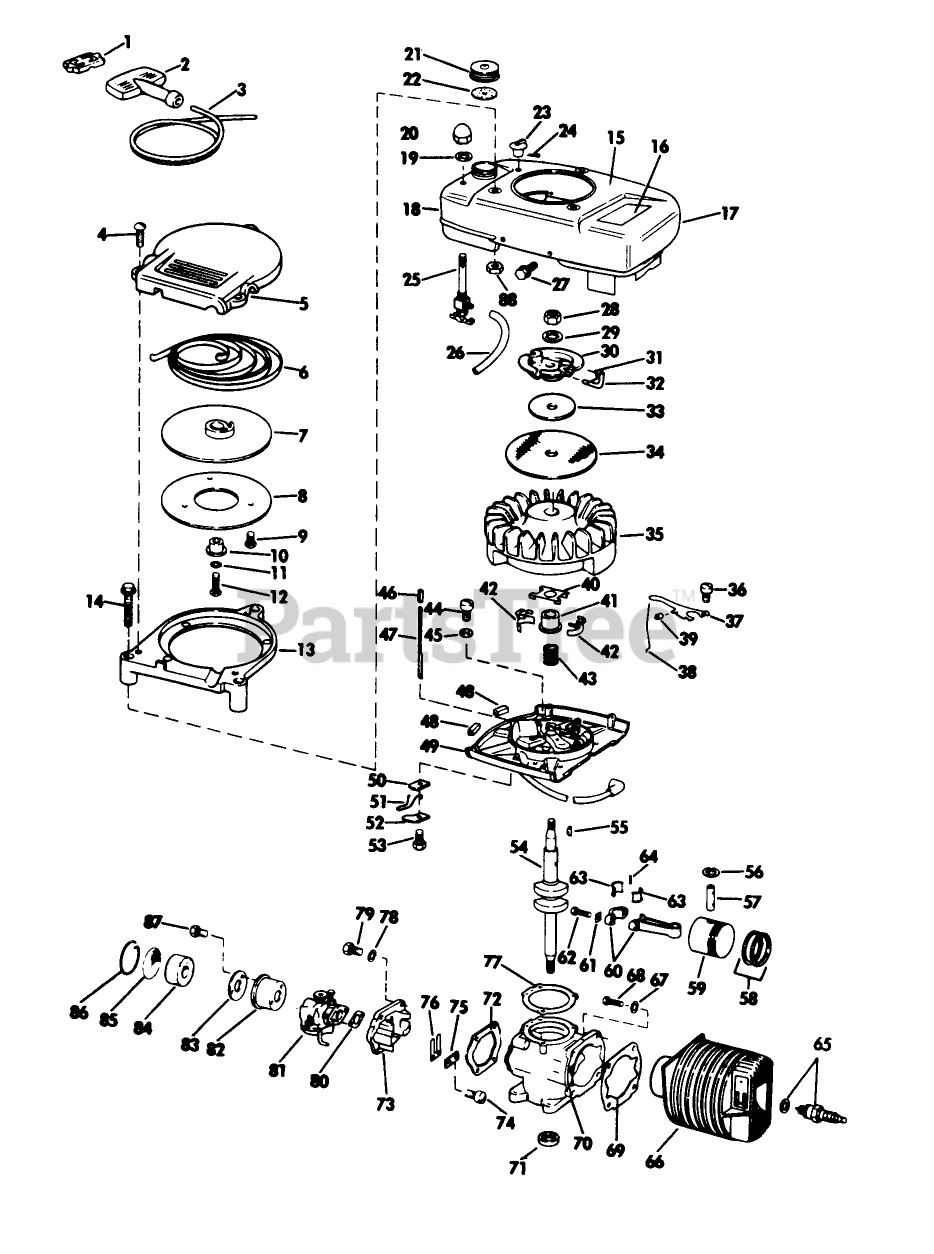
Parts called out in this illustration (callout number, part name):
6	RECOIL SPRING
19	PALNUT S
21	Gas Cap
23	KNOB, CHOKE BAR
24	Cotter Pin-Choke Knob
25	VALVE&SCREEN SM
27	SCREW S
32	PIN - STARTER
37	GOVERNER LEVER AY
38	GOVERNOR ROD S
39	WEAR BLOCK S
40	Yoke-Governor
41	COLLAR S
53	Screw-Shut-Off Switch
56	RING-RETAINING
60	Connecting Rod Assembly
63	LINER ASM
69	GASKET S
75	PLATE-BACKUP, REED
77	GASKET S
79	SCREW S
80	GASKET S
83	BACK-UP PLATE
84	ELEMENT
